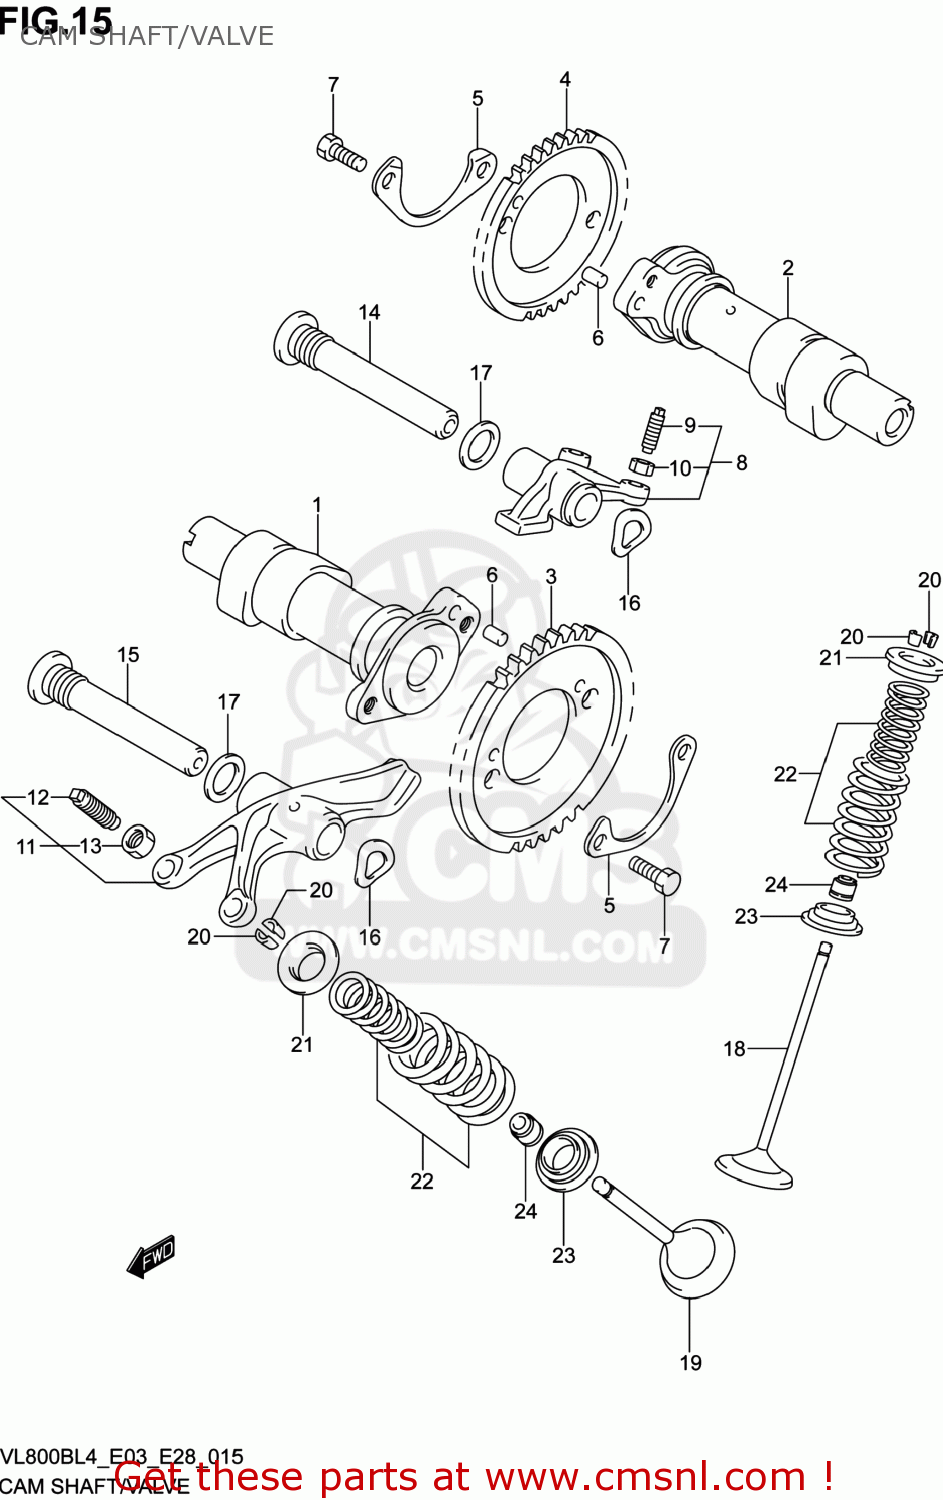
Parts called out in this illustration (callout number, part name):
1	CAMSHAFT,FR
2	CAMSHAFT,RR
3	SPROCKET,CAMSHAFT
4	SPROCKET,CAMSHAFT(NT:42)
5	WASHER,SPROCKET
6	PIN
7	BOLT(6X12.5)
8	ARM COMP,INTAKE VALVE ROCKER
9	SCREW,TAPPET ADJUSTING
10	NUT,ADJUSTING SCREW
11	ARM,EXHAUST VALVE ROCKER FR
12	SCREW,TAPPET ADJUSTING
13	NUT,ADJUSTING SCREW
14	SHAFT,VALVE ROCKER ARM
15	SHAFT,VALVE ROCKER ARM
16	WASHER
17	GASKET(13.8X18.8X4.8) (NAS)
18	VALVE,INTAKE
19	VALVE,EXHAUST
20	COTTER,VALVE
21	RETAINER,VALVE SPRING
22	SPRING SET,VALVE
23	SEAT,VALVE SPRING
24	SEAL,OIL(5.5X11X8.2)
